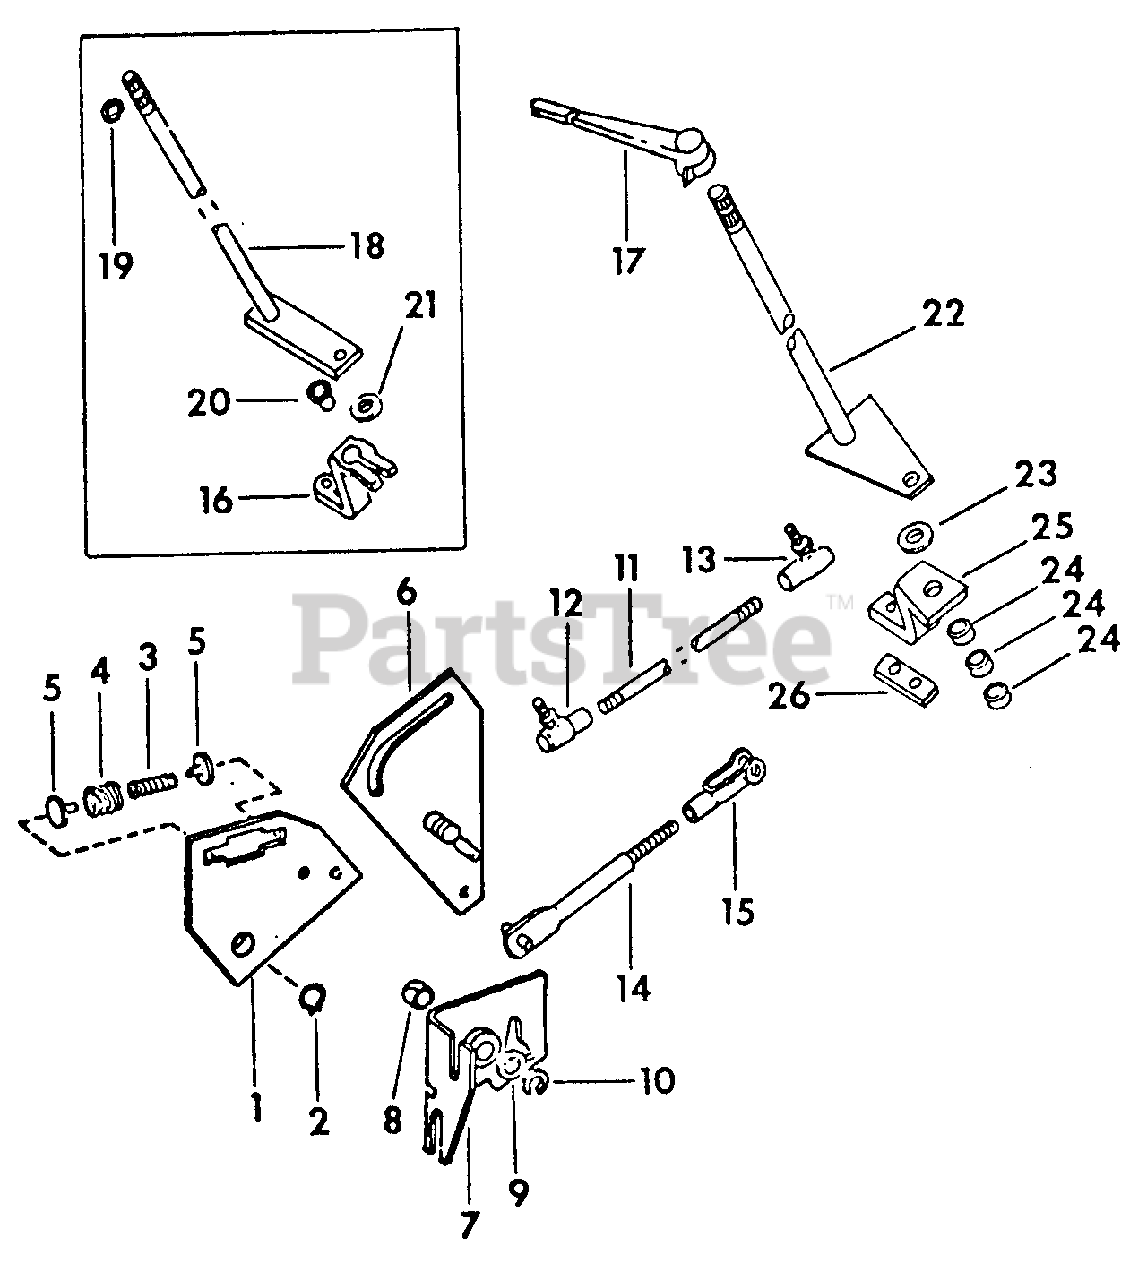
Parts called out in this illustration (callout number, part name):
1	Plate Assy, Damper Spring
2	Ring, Damper Plate Retaining
3	Spring, Damper Light
4	Spring, Damper Heavy
5	Pin, Damper Spring Guide
6	Cam Assy, Speed Control
7	Bracket Assy, Cam Pivot
8	Bushing, Cam Pivot
9	Washer, Cam Retaining
10	Ring, Cam Retaining
11	Stud, Connecting
12	Joint, 5/16-24 X 1-1/2 C-Z RH Thd Ball
13	Joint, 5/16-24 C-Z Ball
14	Rod Assy, Control
15	Clevis, 5/16 Adj Rod End Pin
16	Support, Control Rod
17	Handle, Speed Control
19	Ring, Retaining
20	Bushing, Friction
21	Spacer, Support
22	Shaft Assy, Control
23	Disc, Friction
24	Washer, Belleville Spring
25	Support, Control Rod
26	Shim, Control Support
